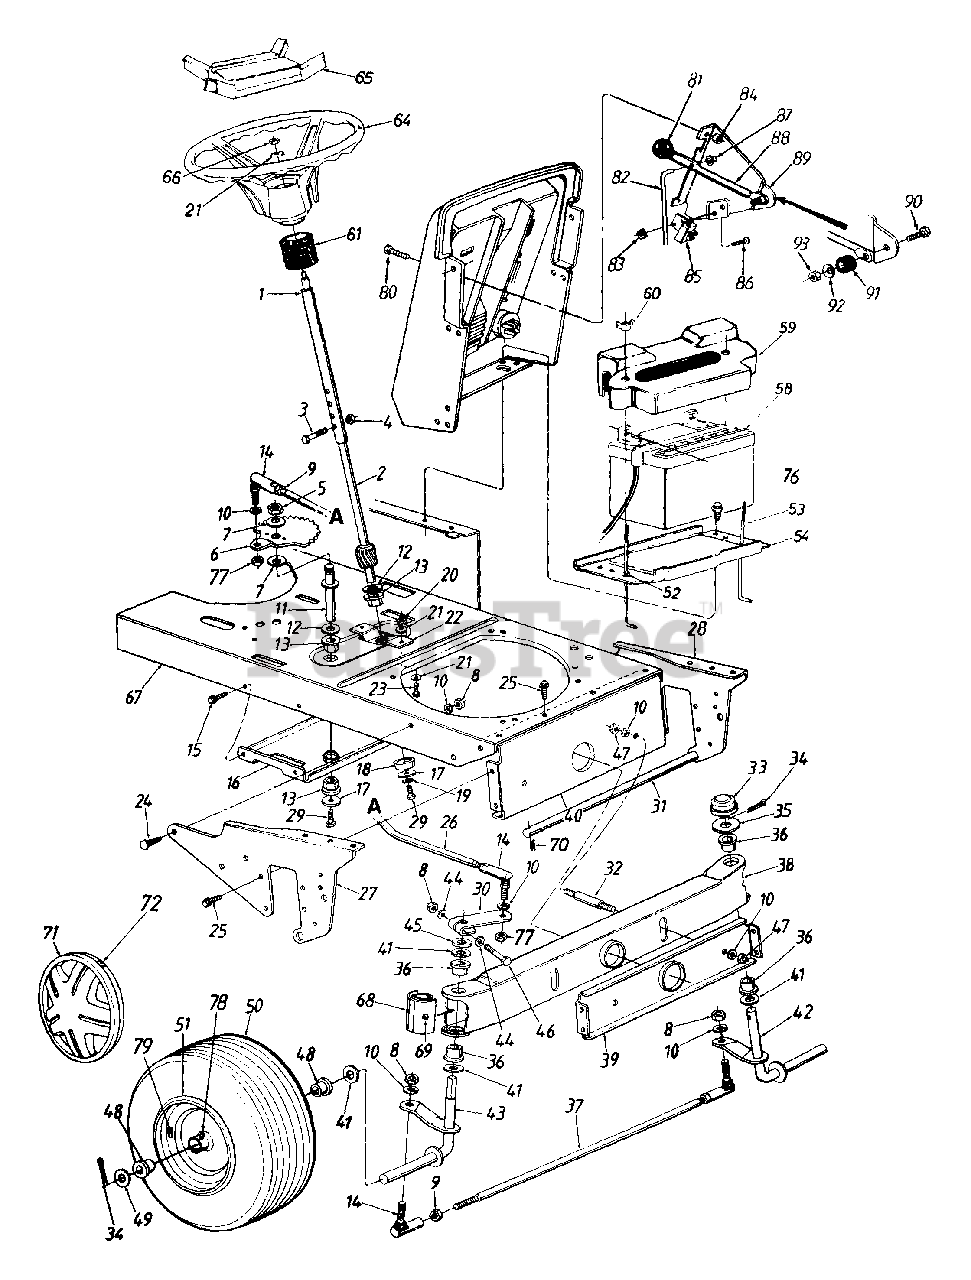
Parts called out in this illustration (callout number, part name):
1	Steering Column Ass'y.
2	Lower Steering Shaft
3	Hex Bolt 1/4-20 x 1.31" Lg.
4	Hex L-Nut 1/4-20 Thd.
5	Hex Nut 5/8-18 Thd.
6	Steering Gear Segment
7	Bell-Wash. 5/8" I.D. x 1.25" O.D.
8	Hex Nut 3/8-24 Thd.
9	Hex Jam Nut 3/8-24 Thd.
10	L-Wash. 3/8" I.D.
11	Steering Gear Segment Shaft
12	Fl-Wash. .64" I.D. x 1.24" O.D.
13	Hex Flange Brg. .63" I.D.
14	Ball Joint Ass'y.
15	Hex Wash. Hd. TT-Tap Scr. 1/4-20 x .5" Lg.
17	Fl-Wash. .33" I.D. x 1.25" O.D.
18	Spacer .985" I.D. x 1.25" O.D.
19	L-Wash. 5/16" I.D.
20	Hex Nut 5/16-24 Thd.
21	Bell-Wash. .345" I.D. x .88" O.D.
24	Ribbed Neck Bolt 3/8-24 x .8" Lg.
25	Hex Wash. TT-Tap Scr. 5/16-18 x .62" Lg.
26	Steering Drag Link
27	Pivot Bar Side Plate - R.H.
28	Pivot Bar Side Plate - L.H.
29	Hex Bolt 5/16-18 x .62" Lg.
30	Steering Arm Ass'y.
31	Deck Connecting Rod
32	Pivot Bar Shld. Bolt 3/8-16 x 5/8" Lg.
33	Cap
34	Cotter Pin 5/32" Dia.
35	Flat Washer
36	Flange Brg. .757" I.D.
37	Tie Rod 20.25" Lg.
38	Pivot Bar Assy.
41	Fl-Wash. .76" I.D. x 1.49" O.D.
42	Front Axle Ass'y. - L.H.
43	Front Axle Ass'y. - R.H.
44	Bowed Washer
45	Spacer .755" I.D. x 1.25" O.D.
46	Hex Bolt 3/8-24 x 2.25" Lg.
47	Hex Nut 3/8-16 Thd.
48	Flange Brg. .75" I.D.
49	Fl-Wash. .71" I.D. x 1.5" O.D.
53	Battery Hold Down Rod
54	Battery Plate
58	Battery (275 Cold Crank Amps)
59	Battery Cover
60	Wing Nut Plastic 1/4-20 Thd.
61	Steering Bellow
64	Steering Wheel
65	Steering Wheel Insert
66	Hex L-Nut 5/16-24 Thd.
69	Grease Fltting
70	Internal Cotter Pin
71	Hub Cap
72	Spring Clip
76	Hex AB-Tap Scr. 1/4 x .62" Lg.
77	Hex Jam L-Nut 3/8-24 Thd.
78	Grease Fltting
79	Air Valve
80	Truss Mach. Scr. 1/4-20 x .5" Lg.
81	Shift Knob
82	Deck Control Knob
83	Hex Sems Nut #10-24 Thd.
84	Hex Sems Nut 1/4-20 Thd.
85	Safety Switch
86	Truss Mach. Scr. #10-24 x .5"
87	Push Nut
88	Blade Clutch Lever
89	Deck Clutch Control Brkt.
90	Hex Bolt 1/4-20 x 1.25" Lg.
91	Rubber Washer
92	Fl-Wash. .281" I.D. x .73"
93	Hex L-Nut 1/4-20 Thd.
